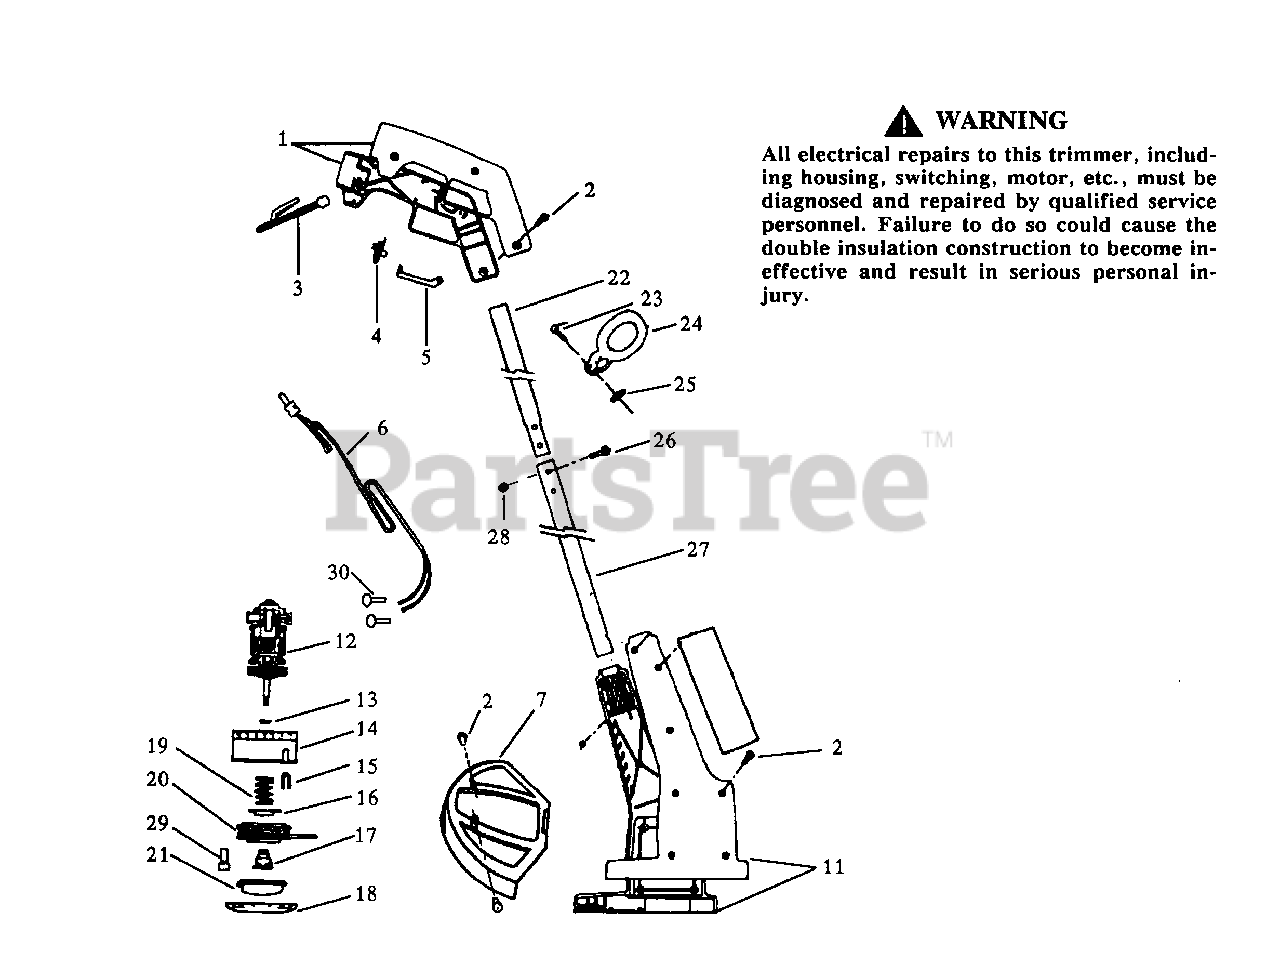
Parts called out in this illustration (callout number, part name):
1	Trigger Handle
3	Cord Retainer
4	On-Off Switch
5	Trigger Switch
6	Wiring Harness
11	Motor Housing Set
12	Motor Assembly
15	Line Saver
17	Drive Gear
20	Spool w/Line
21	Tap Button
22	upper Tube
24	Assist Handle
25	Wing nut
27	lower Tube
28	Locknut
30	Connector
